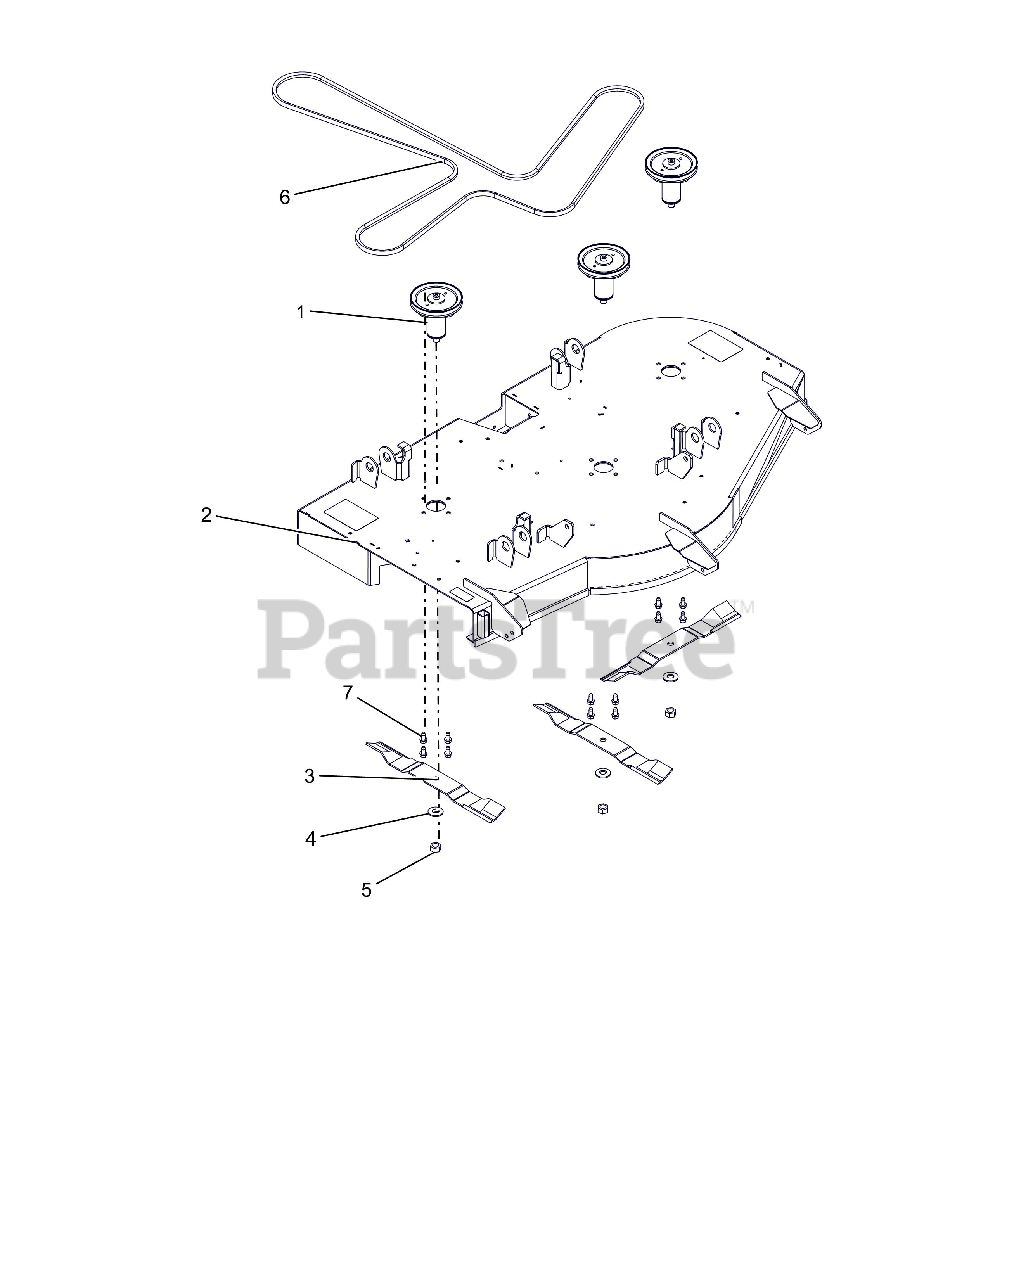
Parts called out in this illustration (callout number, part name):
1	KIT, DECK SPINDLE ASM-52
2	KIT, 52" ARIENS DECK W/DECALS
3	BLADE, 18" - 30 DEG .5 OFFSET
4	WSHR-BLVL .669X1.535X.138
5	NUT-HEX .62-18 YWZC
6	V-BELT, HA-WRAPPED
7	@SCR-TAP .38-16X.75 HWH TR YWZ
